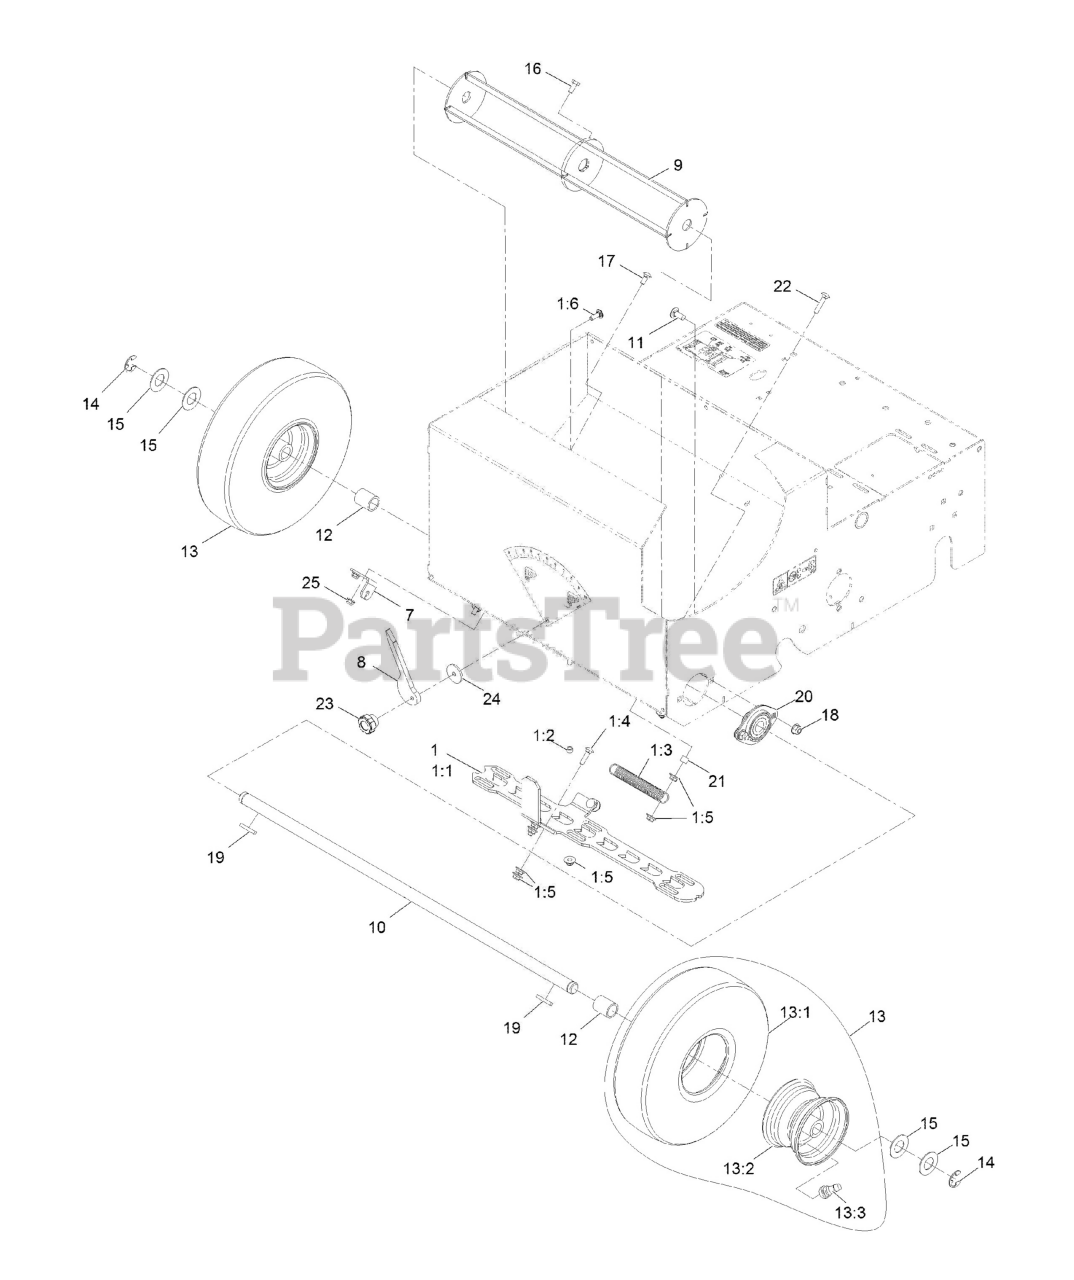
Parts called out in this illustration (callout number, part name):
1	SEED GATE KIT
1:1	GATE-SEED
1:3	BOLT-CARR
1:5	SCREW-CARR
1:6	SPRING-EXTENSION
7	BRACKET-FLOW, SEED
8	GAUGE-FLOW, SEED
10	AXLE-FRONT
11	SCREW-CARR
13	WHEEL ASM
13:2	WHEEL-RIM
13:3	VALVE
15	WASHER-FLAT
16	SCREW-HH
17	SCREW-CARR
18	NUT-HF, NI
19	KEY-SQUARE
20	BEARING
22	SCREW-CARR
23	KNOB-CHUTE
24	WASHER
